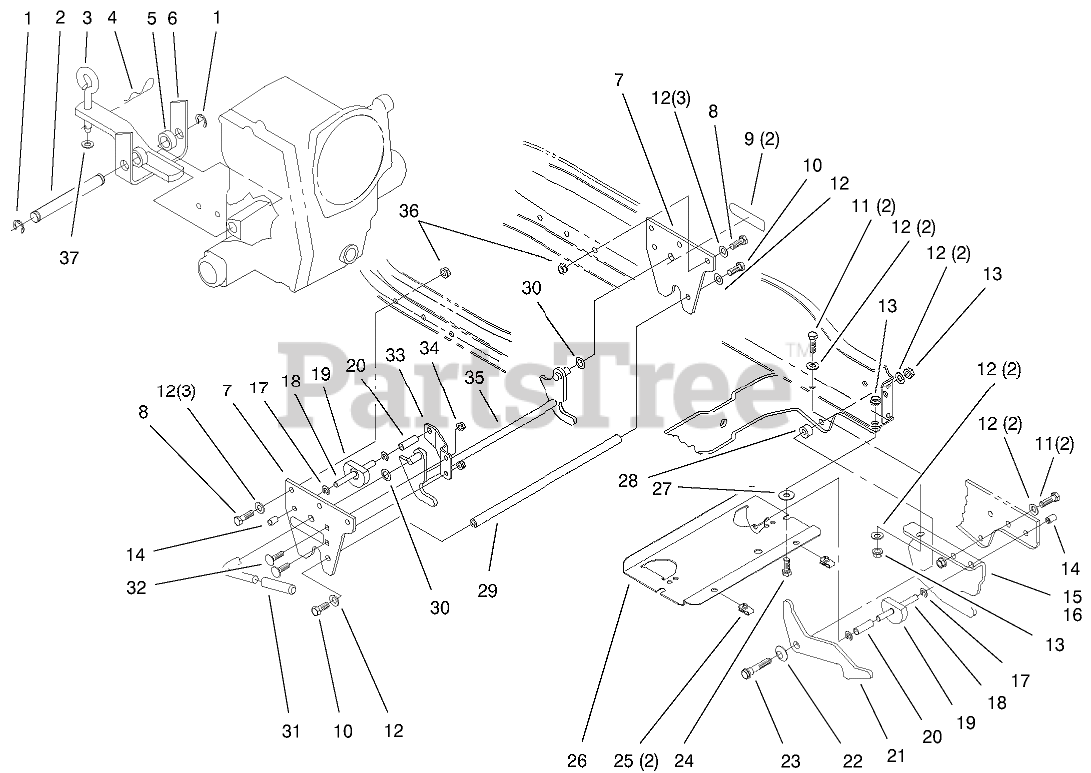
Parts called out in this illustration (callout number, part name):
1	E-RING
2	PIN-STATIONARY HITCH
3	PIN-TOOL
4	PIN-HAIR
5	SPACER
7	PLATE-HITCH
8	SCREW-HH
9	DECAL-ATTACH A MATIC
10	SCREW-HH, LOCK
11	SCREW-HH
12	WASHER-FLAT
13	NUT-LOCK, NI
14	CAP-ROD, PLUNGER
15	HANGER-RH
16	HANGER-LH
17	RING-RETAINING
18	ROD-LOCK
19	LOCK-LATCH
20	SPRING
21	LATCH-BOX, PULLEY
22	WASHER-SPRING
23	BOLT-SHOULDER
24	SCREW-HH
26	TRAY-BATTERY
27	WASHER-TOP THRUST
28	SPACER
29	ROD-SPACER
30	WASHER
31	GRIP
32	BOLT-CARR
33	BRACKET-ARM, MID
34	NUT-LOCK, NI
37	WASHER-FLAT
